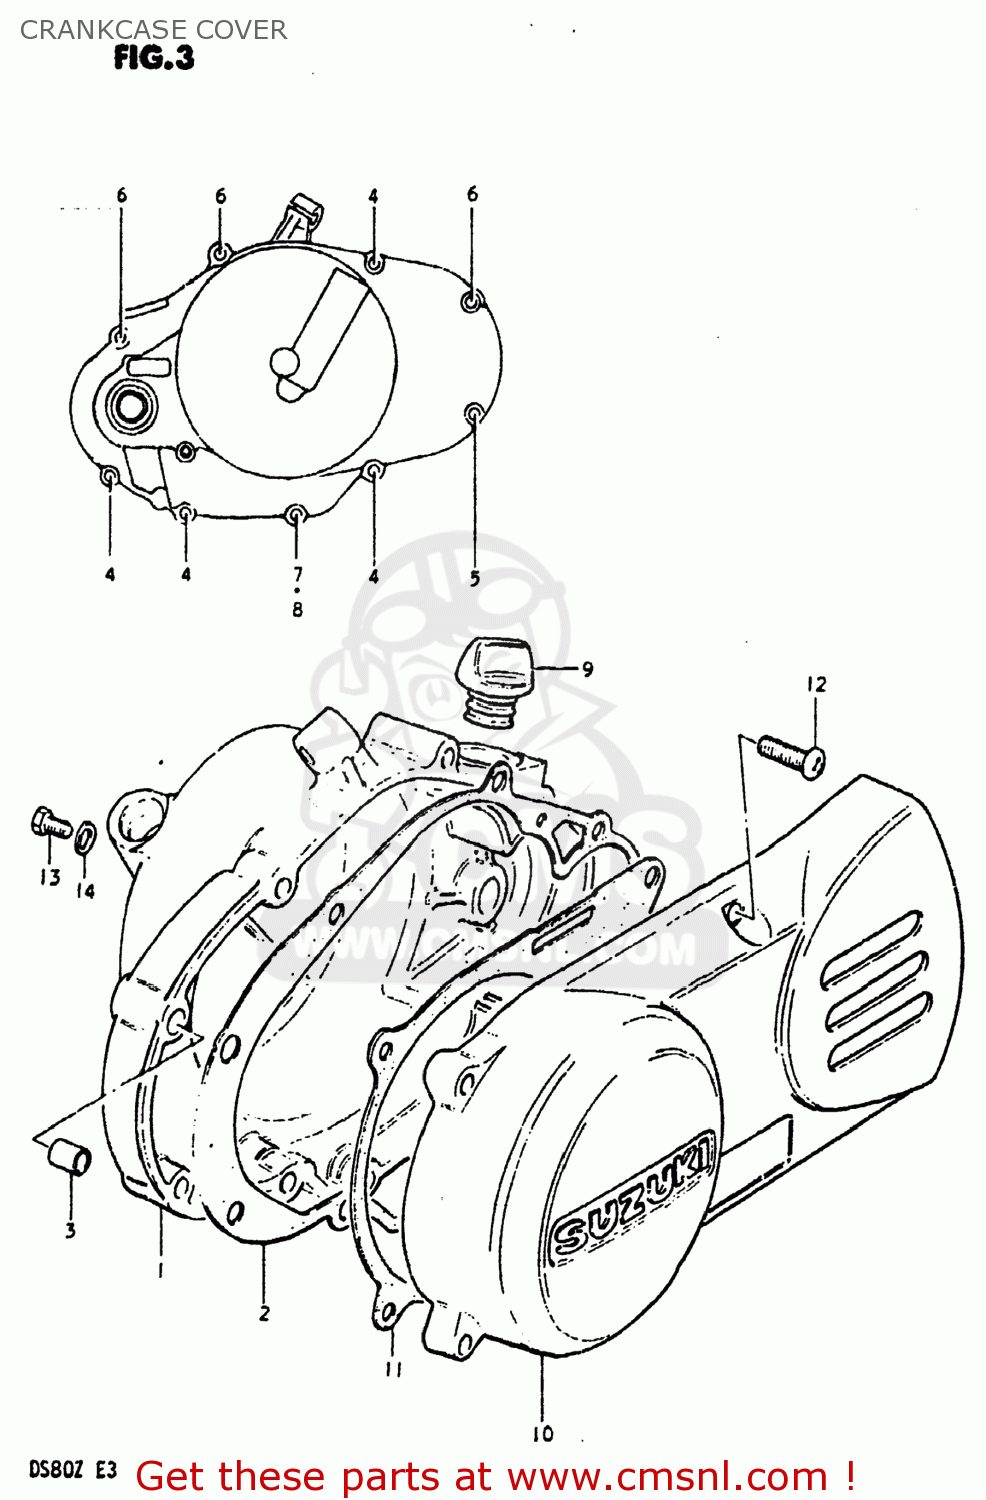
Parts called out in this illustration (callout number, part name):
1	COVER,CLUTCH
2	GASKET,CLUTCH COVER (MCA)
3	PIN
4	SCREW
5	SCREW 6X30
6	SCREW
7	SCREW (6X35)
8	GASKET(6.2X11X1).2 (NAS)
9	PLUG
10	COVER,MAGNETO
11	GASKET,MAGNETO COVER (NAS)
12	SCREW
13	SCREW(6X10)
14	GASKET(6.2X11X1) (NAS)
